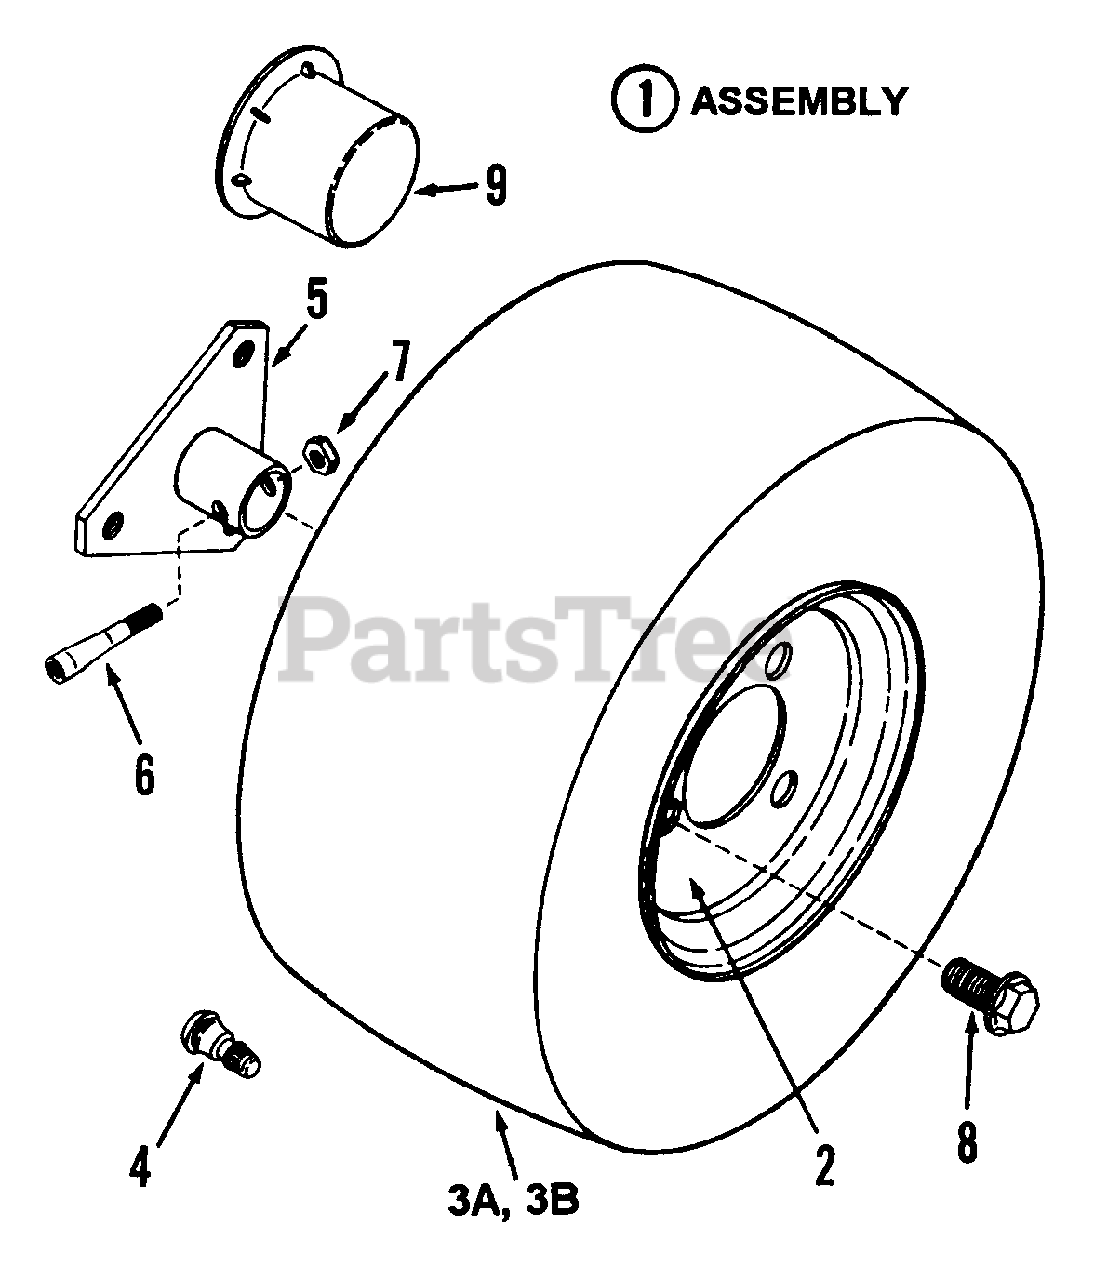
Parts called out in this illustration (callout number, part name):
1	ASSEMBLY, Rear Tire & Rim 18x6.50-8
1	ASSEMBLY, Rear Tire & Rim 21x6.50-8 (NLA)
2	RIM, LT16 Rear Wheel
3A	TIRE, 18 x 6.50 x 8
3B	TIRE, 21 x 7.00 x 8 (NLA)
4	VALVE, Air
5	HUB, Wheel 3 Hole 1" ID
6	BOLT, Wheel Hub, Tapered 5/16-24 x 2"
7	NUT, 5/16-24 Lock
8	BOLT, Lug 1/2-20 x 3/4" HHCS
9	HUB-CAP
